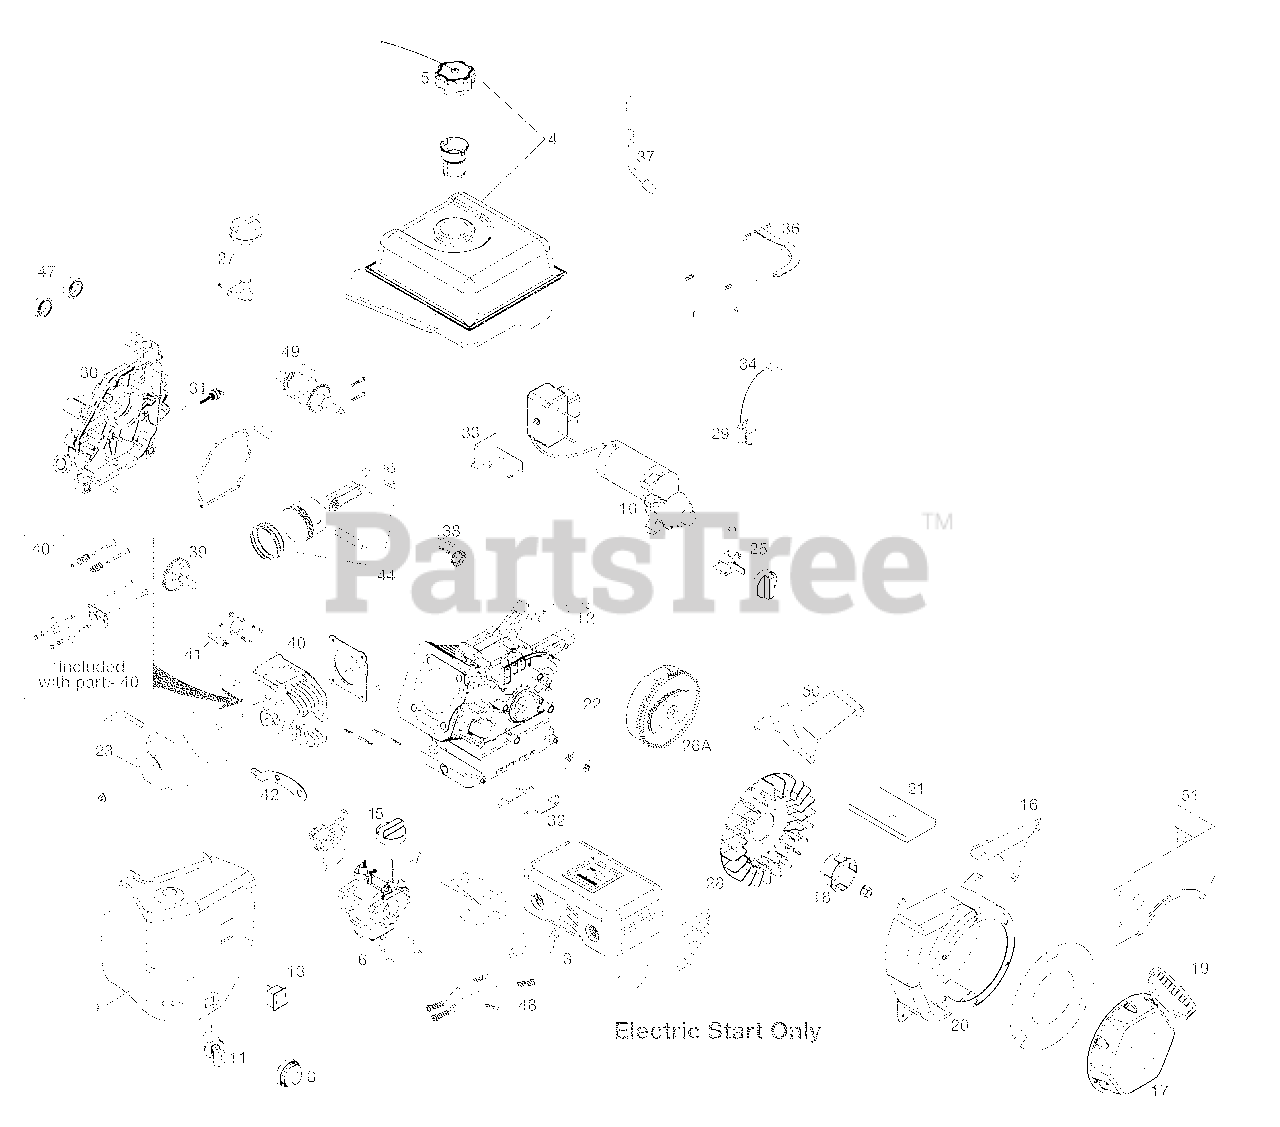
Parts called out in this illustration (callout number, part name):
1	HEATER BOX ASSEMBLY-SNOW
3	MUFFLER ASSEMBLY-SNOW
4	FUEL TANK ASSEMBLY-SNOW
5	FUEL TANK CAP-OVERSIZED (CLICK STYLE)-SNOW
6	CARBURETOR ASSEMBLY-SNOW
7	CHOKE LEVER,CARBURETOR-SNOW
8	PRIMER BULB ASSEMBLY W/HOSE-SNOW
10	ELECTRIC STARTER ASSEMBLY-SNOW
11	KEY SWITCH ASSEMBLY-SNOW
12	CDI BOX ASSEMBLY-SNOW
13	ON/OFF SWITCH-SNOW
15	CHOKE KNOB-SNOW
16	GOVERNOR LINKAGE SHIELD PLATE-SNOW
17	RECOIL STARTER ASSEMBLY-SNOW
18	STARTER CUP SMALL-SNOW
19	STARTER GRIP-SNOW
20	BLOWER HOUSING ASSEMBLY, ELECTRIC START-SNOW
21	SHIELD, CYLINDER
22	SHIELD, UNDER FLYWHEEL CHARGING SYSTEM-SNOW
23	VALVE COVER
25	FUEL PETCOCK, SNOW
26	FLYWHEEL ASSEMBLY, ELECTRIC START-SNOW
26A	FLYWHEEL ASSEMBLY, MANUAL START-SNOW
27	HIGHOIL FILL ASSY KIT, SNOW
28	FLYWHEEL FAN
29	IGNITION COIL ASSY
30	CRANKCASE COVER ASSY
31	NON-REMOVABLE OIL PLUG
32	CHARGING COIL AC/DC
33	ELECTRIC STARTER BRACKET
34	SPARK PLUG BOOT
36	GOVERNOR ARM ASSY
37	GOVERNOR SHAFT
38	GOVERNOR GEAR ASSEMBLY
40	CYLINDER HEAD ASSY
41	SPARK PLUG
42	CDI BOX BRACKET-SNOW
44	PISTON AND ROD ASSY
46	VAPOR SHIELD
48	WIRE HARNESS
49	CRANKSHAFT
50	TOP SHIELD
51	FUEL TANK SKIRT
